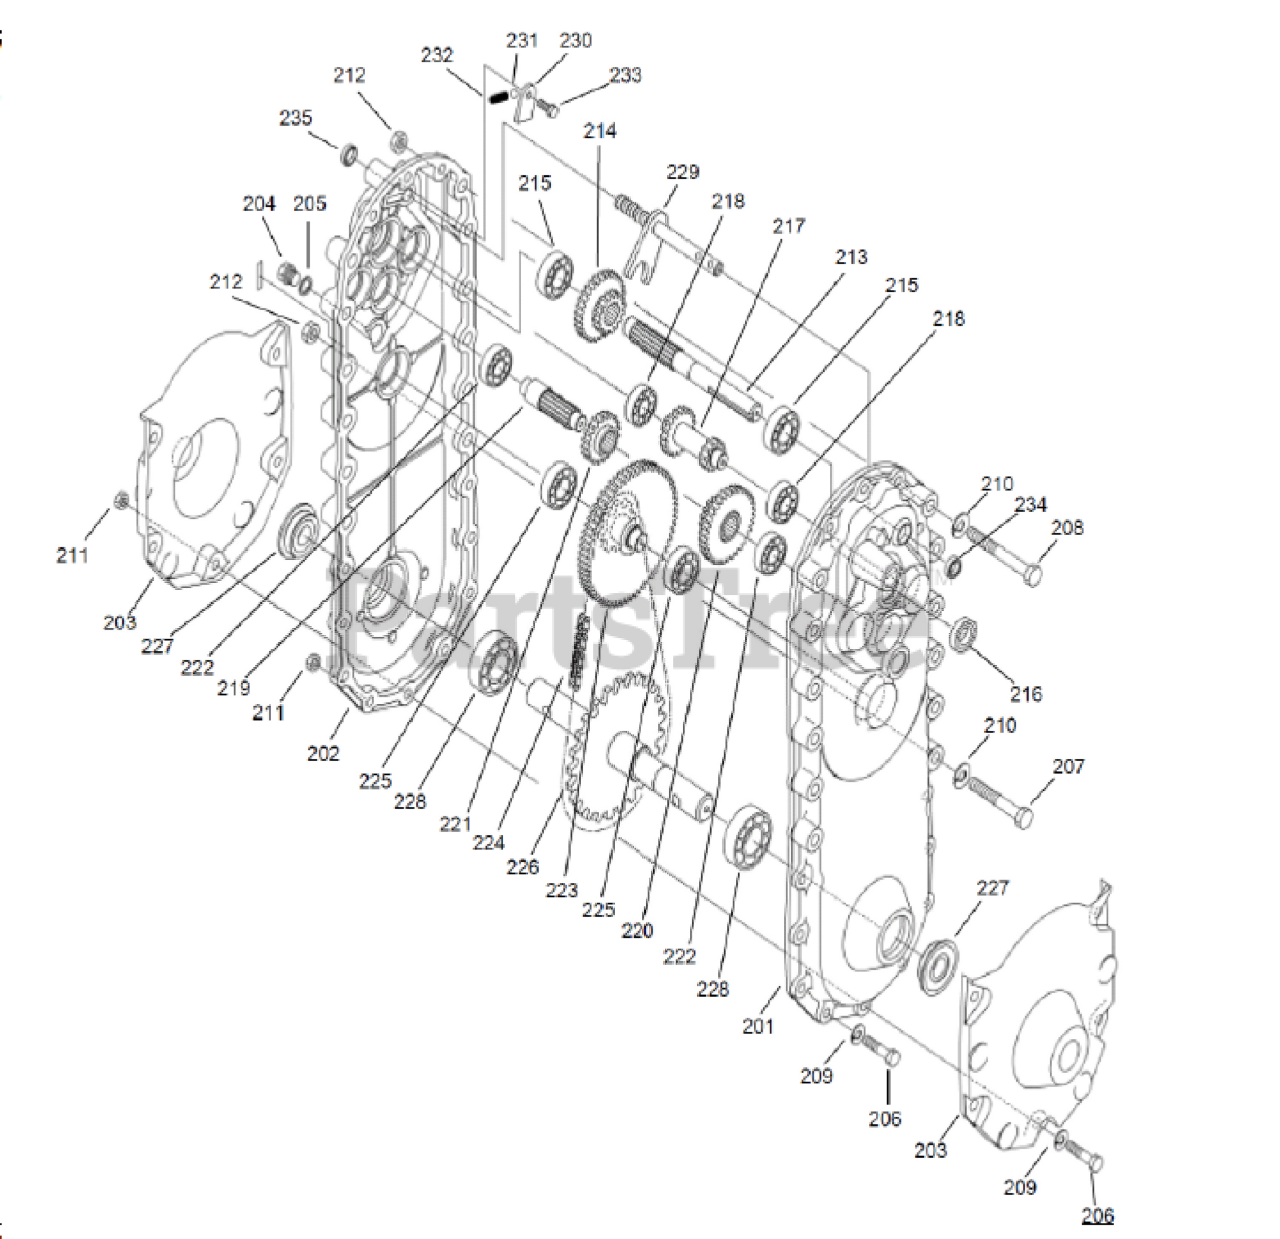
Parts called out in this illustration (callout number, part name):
209	WASHER
212	NUT
215	BALL BEARING 0002010226
225	BALL BEARING 0002010226
228	BALL BEARING 6205
232	SPRING 0002010237
